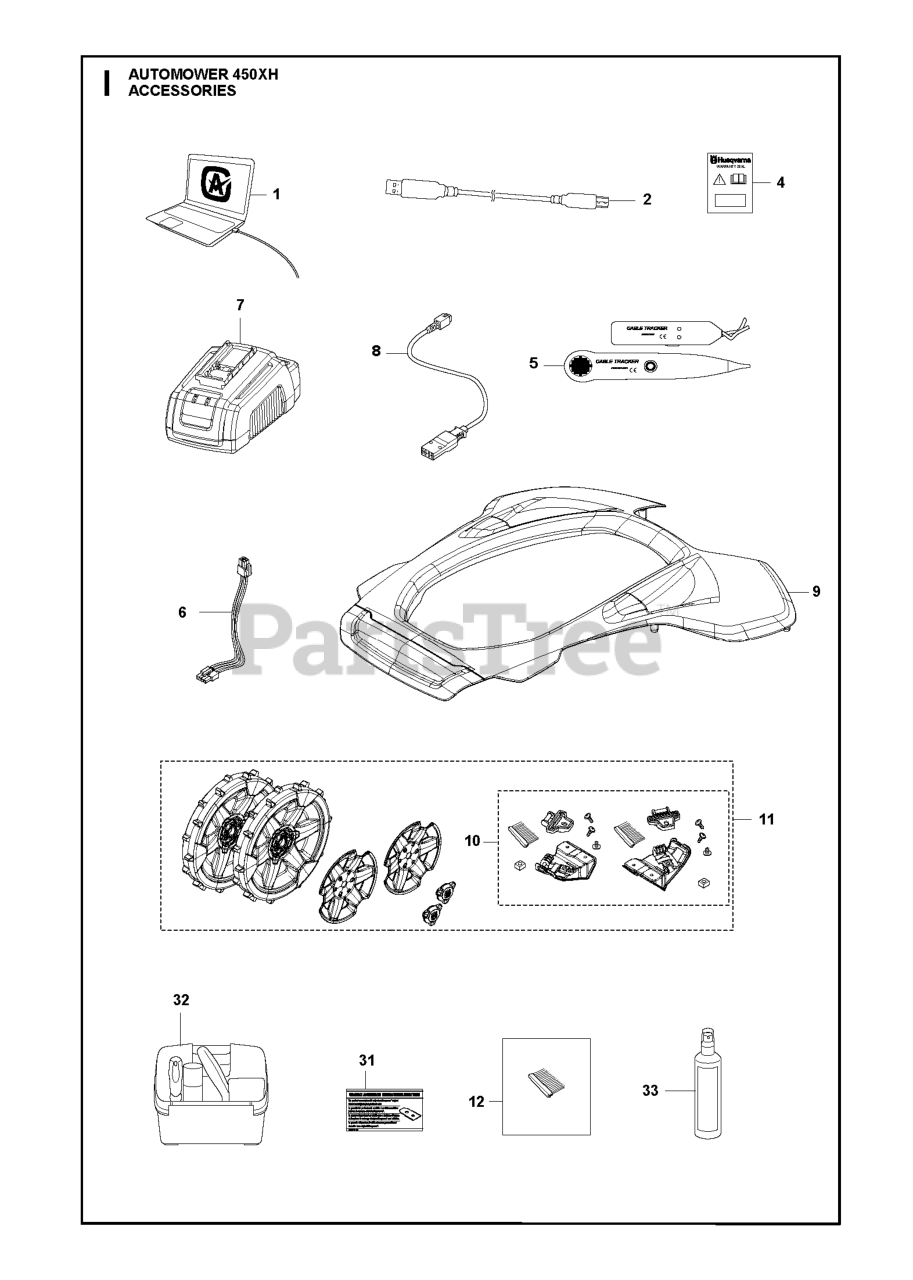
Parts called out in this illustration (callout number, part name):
2	CABLE WHITE ALT GREY
4	LABEL WARRANTY SEAL DEALER
5	TEST EQUIPMENT
6	WIRING ASSY BATTERY CABLE
7	CHARGER BATTERY TEST
8	CABLE ASSY QUICK CHARGER
9	TOP COVER ORANGE/ 450
9	BODY KIT
9	TOP COVER WHITE/ 450
10	BRUSH KIT 430/450
11	REAR WHEEL KIT W/ BRUSHES
12	WHEEL BRUSH REFILL KIT
31	DECAL WARNING ORIGINAL BLADE E
32	CLEANING AND MAITENANCE KIT AM
33	AUTOMOWER ACCY
